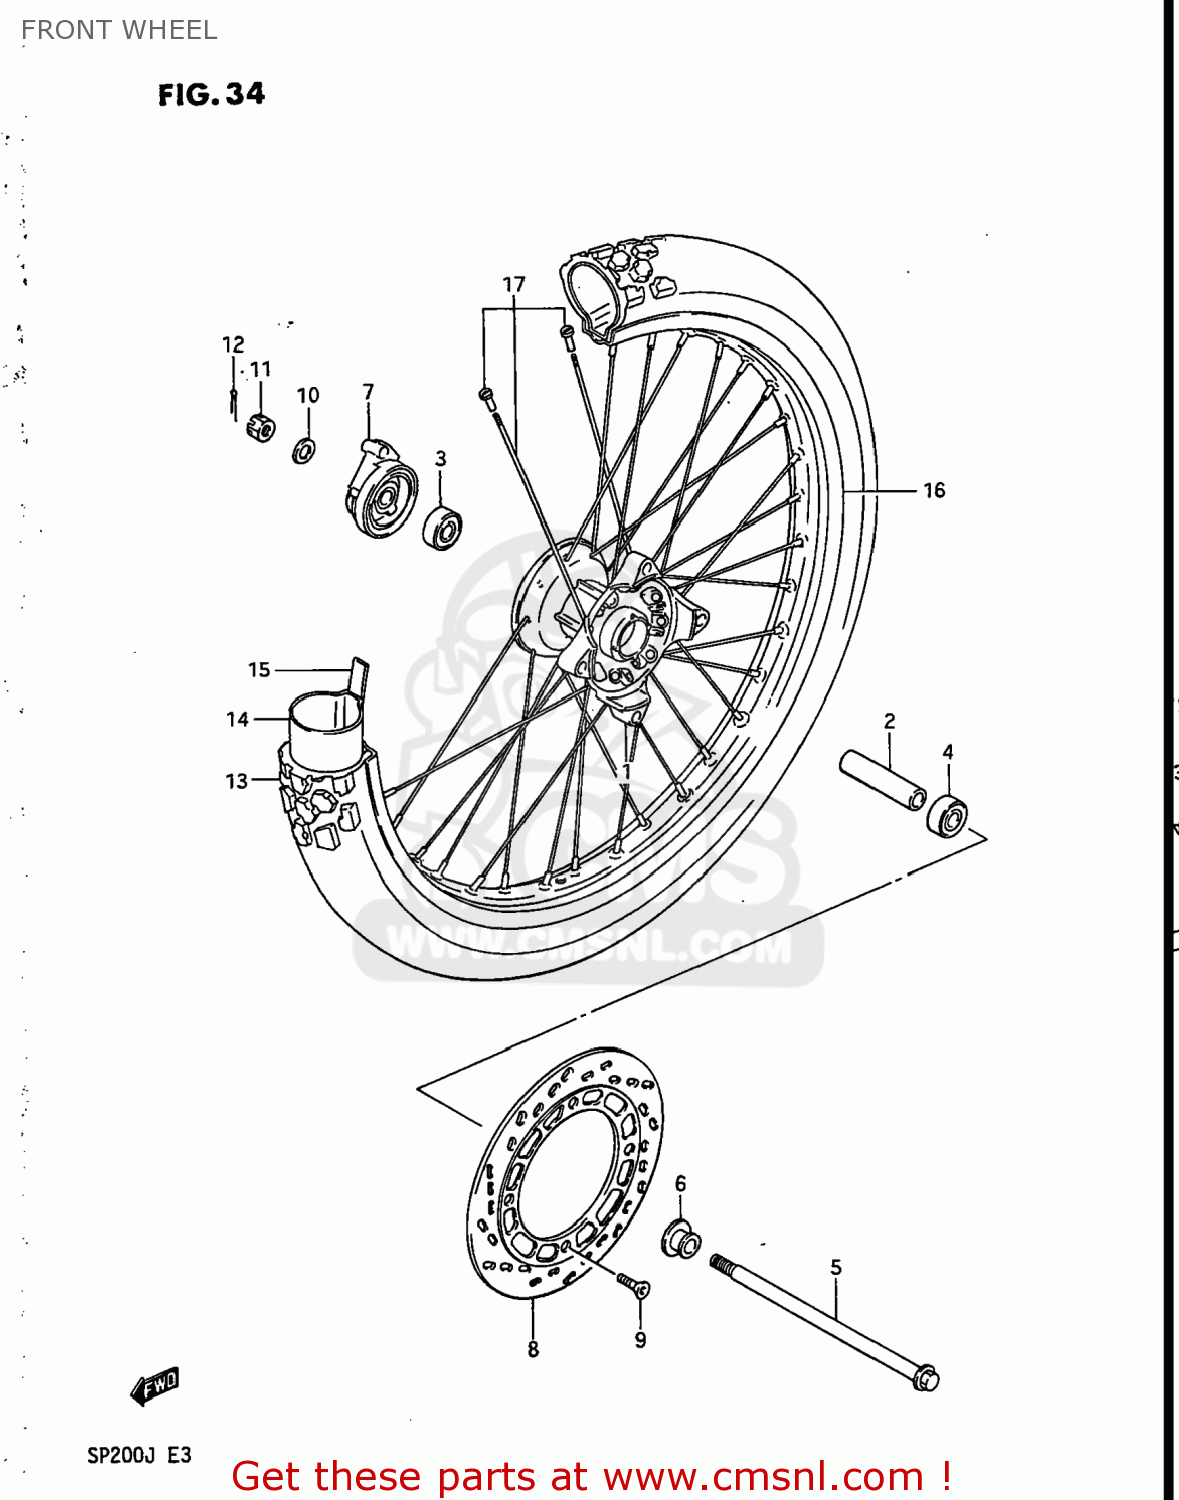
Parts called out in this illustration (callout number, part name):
1	HUB,FRONT
2	SPACER (12.6X19X60.5)
3	BEARING
4	BEARING, RH
5	AXLE,FRONT
6	SPACER,FRONT AXLE,RIGHT
7	BOX ASSY,SPEEDOMETER GEAR
8	DISC,BRAKE
9	BOLT,BRAKE DISC
10	WASHER
11	NUT 12MM
12	COTTER PIN
13	TIRE,FRONT
14	TUBE
15	PROTECTOR,WHEEL,INNER
16	RIM,FRONT WHEEL
17	SPOKE SET,FR WHEEL
